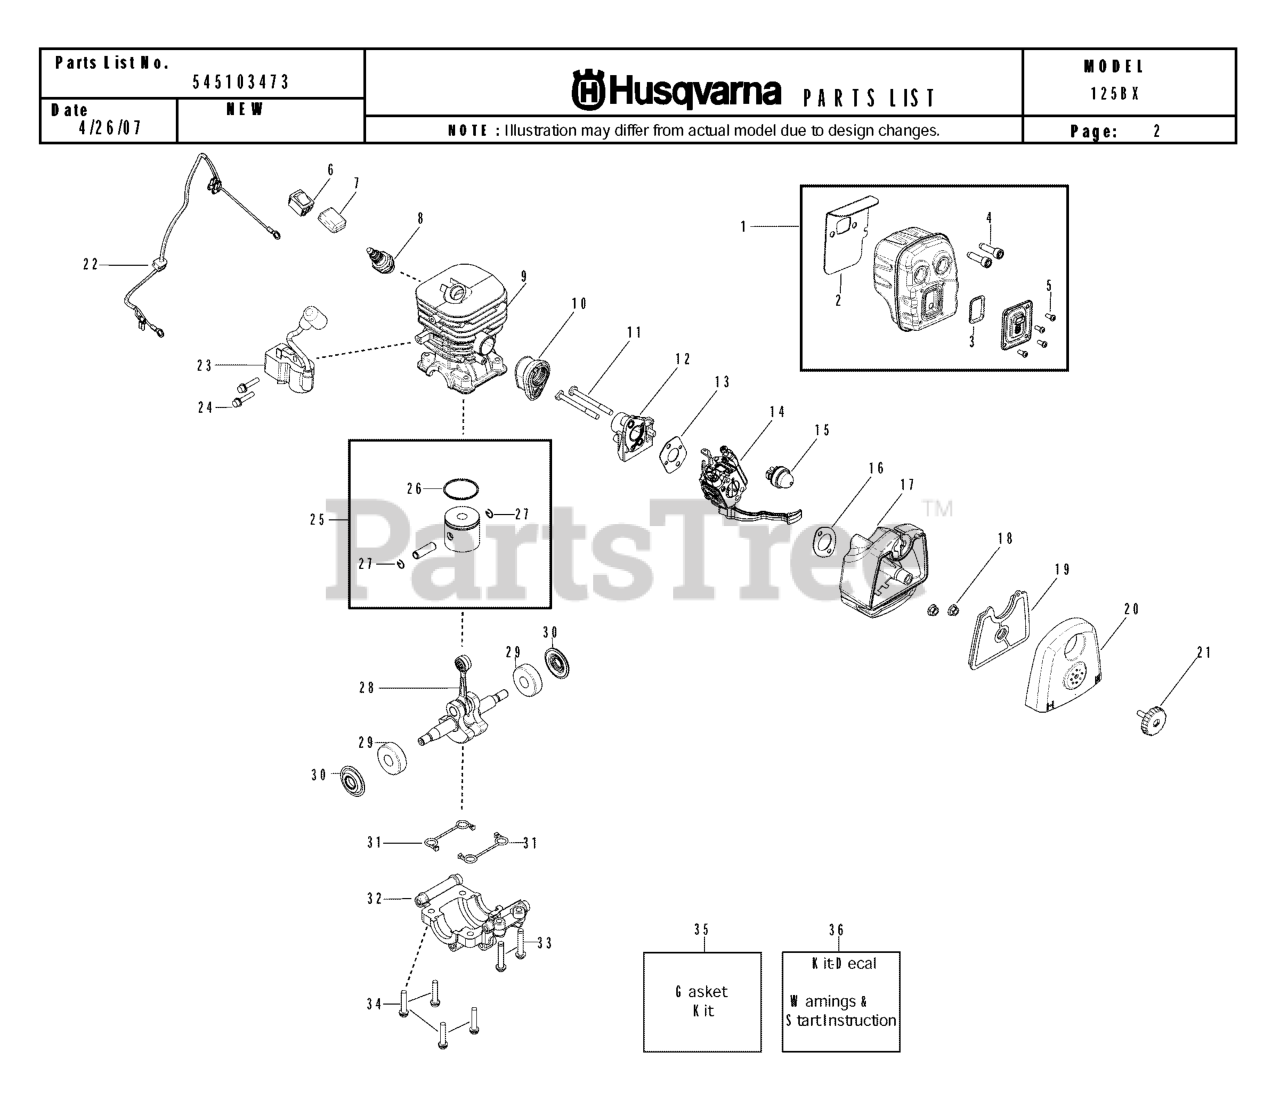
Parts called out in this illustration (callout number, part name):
1	ASSY, MUFFLER
3	KIT, SPARK SCREEN
4	BOLT MUFFLER
5	SCREW-6-19X5/16PLAST PA
6	KIT SWITCH
7	PROTECTOR, SWITCH
8	Accy - Spark Plug (RCJ6-Y)
9	CYLINDER -CHROME
10	BOOT, CARB
12	PLATE, CARB
14	KIT CARBURETOR
17	BASE, AIRBOX
19	Air Filters
20	COVER, AIRBOX
21	KNOB ASSY AIRBOX COVER
22	ASSY, LEADWIRE
23	IGNITION MODULE
24	SCREW M4 X .70 TT 16MM
25	KIT - PISTON
26	RING PISTON
27	WRIST PIN RET.
28	KIT, CRANKSHAFT
29	BEARING RADIAL BALL (6201)
30	CRANKSHAFT SEAL
32	CAP - BEARING
34	SCREW-M5-0.8 X 25MM(TAP)
36	KIT, DECAL
